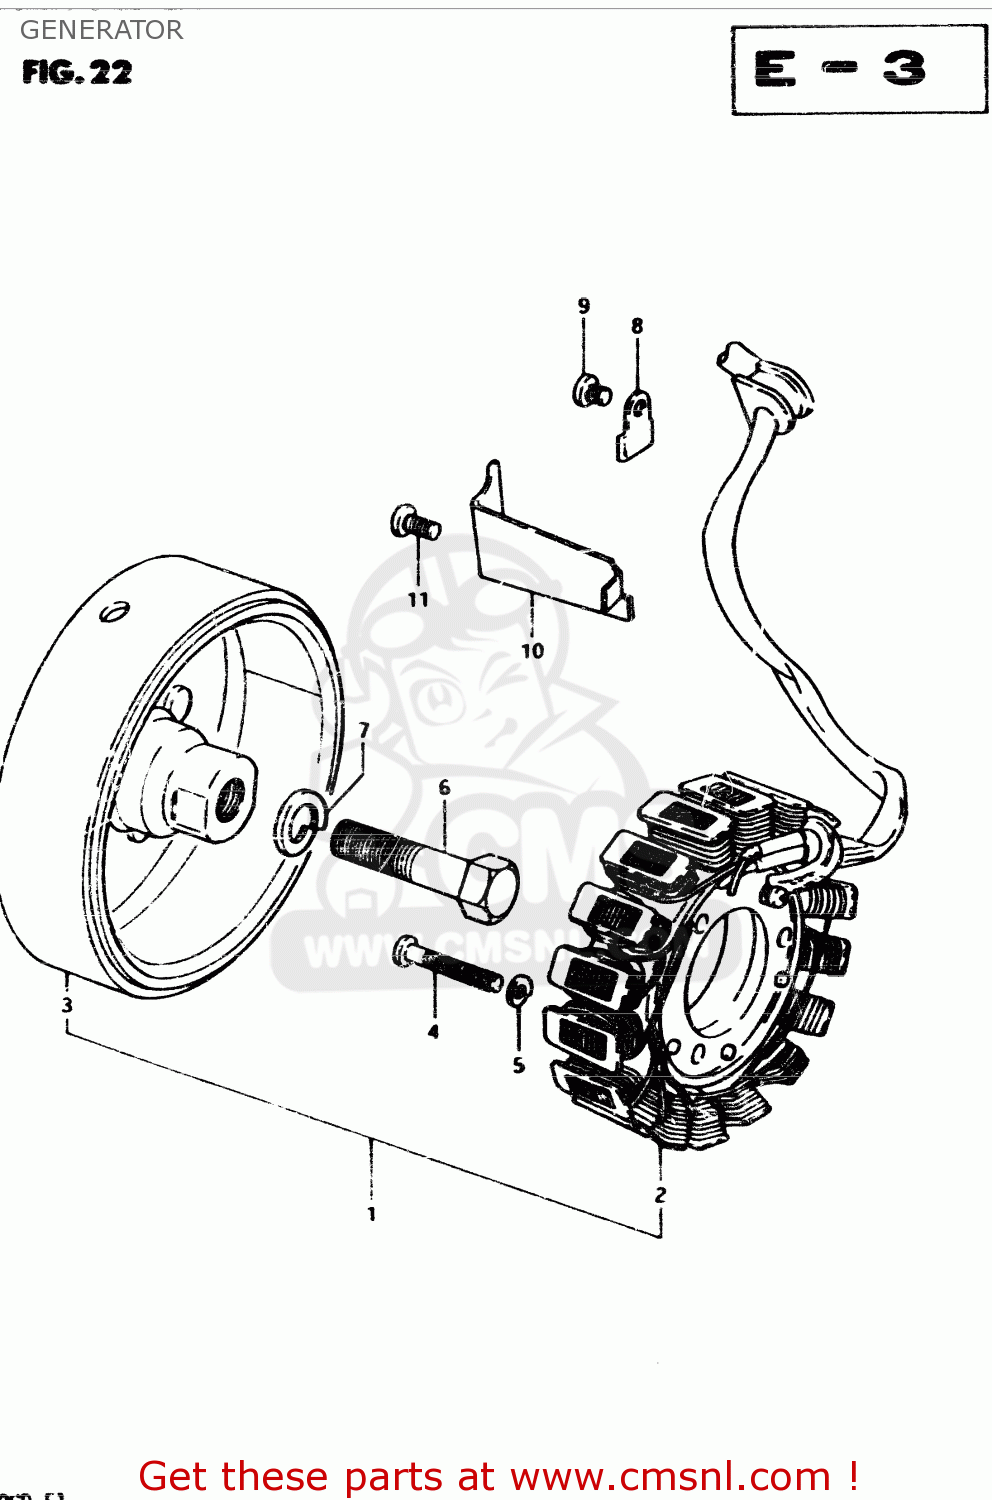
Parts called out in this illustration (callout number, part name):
1	GENERATOR ASSEMBLY
2	STATOR ASSEMBLY
3	ROTOR ASSEMBLY
4	SCREW
5	LOCK WASHER
6	BOLT 12X45
7	WASHER,LOCK 12
8	CLAMP,GENERATOR LEAD WIRE
9	SCREW
10	CLAMP,GENERATOR LEAD WIRE
11	SCREW
